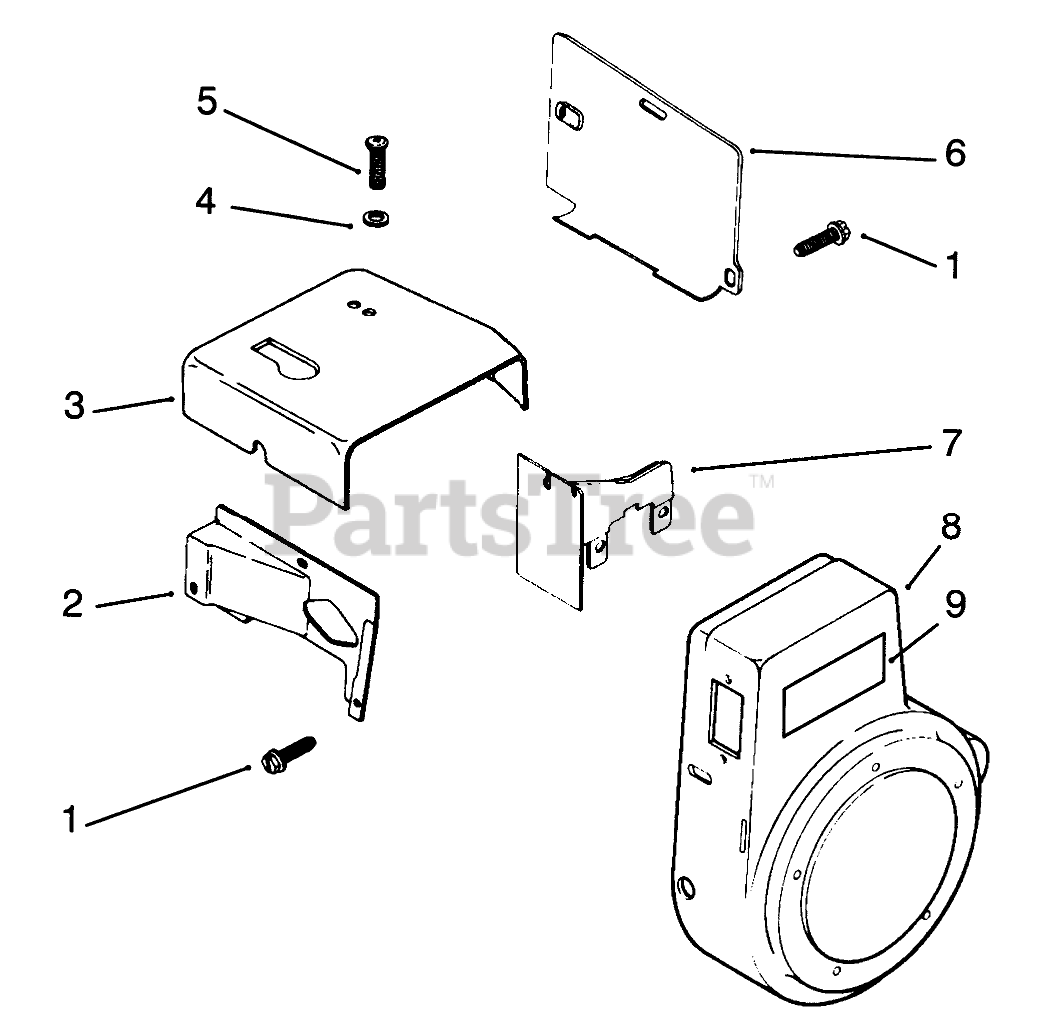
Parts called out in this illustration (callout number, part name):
1	Screw Hex Hd
2	Baffle-SideAir
3	Baffle-Head
4	Washer
5	Screw-Pozidriv T.H.
6	Baffle-Cylinder
7	Baffle-Inner
8	Blower Housing
9	Decal-HP
